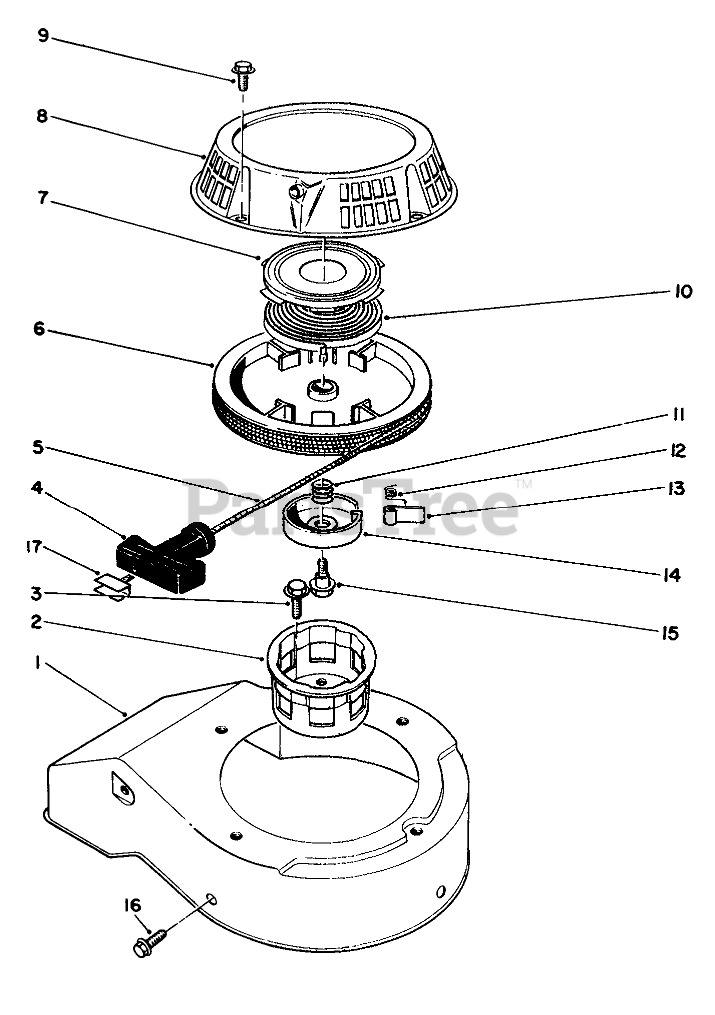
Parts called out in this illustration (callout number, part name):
1	Cover-Cooling Fan
2	PULLEY-CUP, STARTER
4	RETAINER
5	SPRING
7	Retainer-Recoil Spring
8	CASE-STARTER
9	SCREW-HHF
10	Spring-Recoil
11	ROPE-STARTER
12	STOP-ROPE
13	HANDLE-RECOIL
14	SPRING
18	Insert Handle
19	Staple
